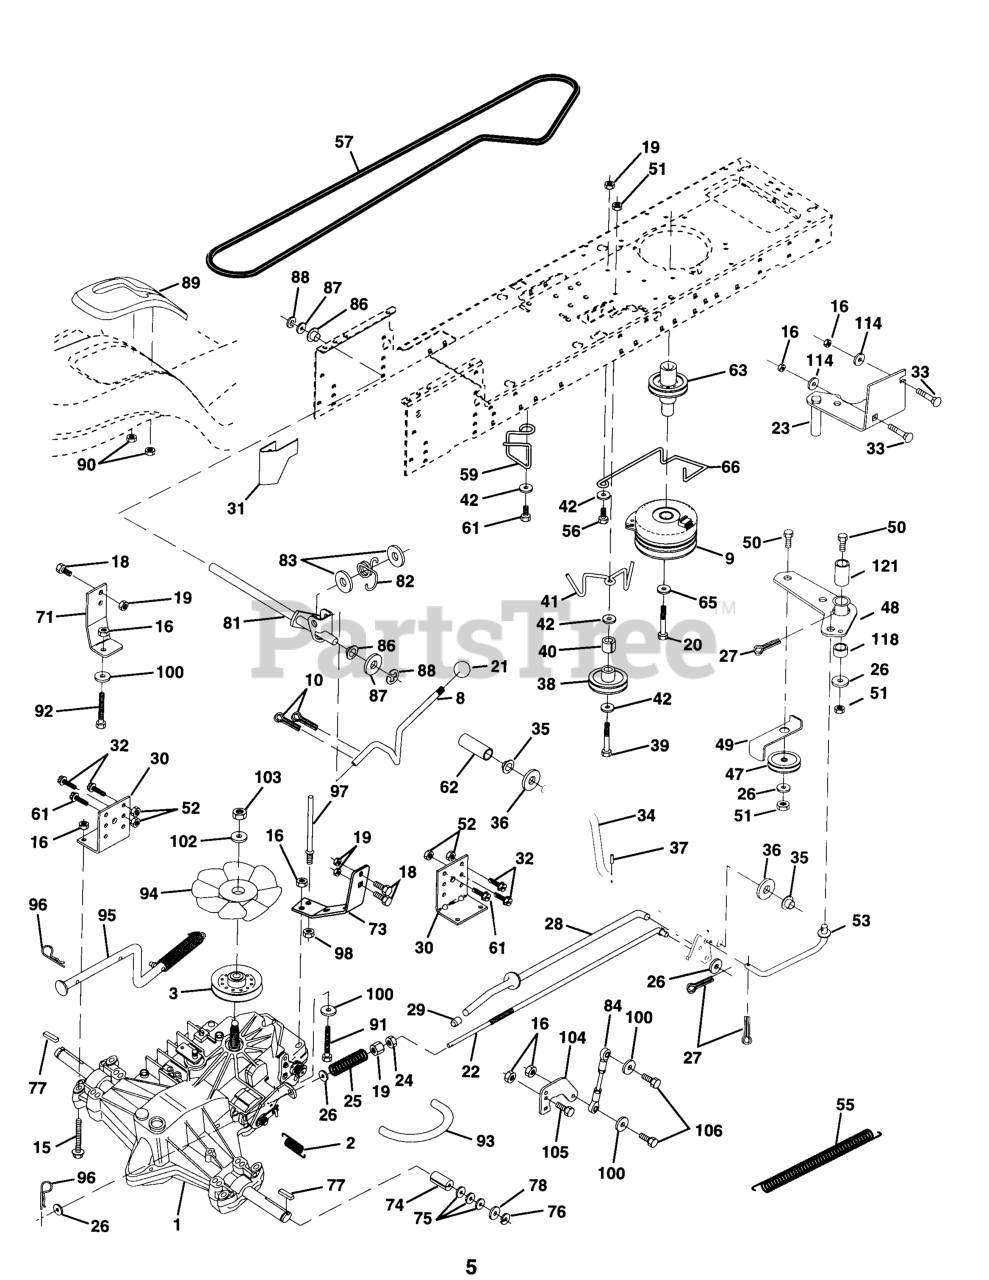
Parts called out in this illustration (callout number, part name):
2	SPRING BRAKE
3	PULLEY, TRANSAXLE
8	ROD SHIFT FENDER
9	CLUTCH.ELECT.EVX.
10	PIN COTTER
15	BOLT HEX 5/16-18 GR 5
16	NUT.71038.31-18.HEX.NYLOCK
18	BOLT
19	NUT
20	BOLT HEX
21	KNOB.DELUXE.(PISTOL.GRIP).BLAC
22	ROD BRAKE HYDRO
23	BRACKET, ASM CLUTCH MTG
24	NUT
25	SPRING ROD LT
26	WASHER
27	COTTER PIN
28	ROD BRAKE PARK LT
29	PLUNGER CAP
30	BRACKET TRANSAXLE
31	KEEPER BELT LH
32	BOLT
33	RP BOLT 5/16-18 X3/4 ZN/YEL GR
34	SHAFT, FOOT PEDAL
35	BEARING.NYLON
36	WASHER LT
37	DRIVE PIN
38	PULLEY.IDLER.FLAT
41	KEEPER, BELT IDLER
42	WASHER
47	IDLER PULLEY
48	BELLCRANK ASSEMBLY
49	RETAIN BELT
50	BOLT
52	LOCKNUT
53	LINK, CLUTCH LT
55	SPRING, RETURN LT
57	DRIVE BELT, LTH & YTH TRACTORS
59	KEEPER CENTER SPAN
61	SCREW
62	COVER, PEDAL (1 2)
63	PULLEY, CLUTCH ELECT EVX
65	LOCKWASHER
66	KEEPER BELT ENGINE
71	STRAP LH TORQUE
73	STRAP TORQUE RH HYDRO
74	SPACER SPLIT
77	SQUARE KEY
81	SHAFT ASSY
82	SPRING,TORSION
83	WASHER
84	ROD.TIE.BALL.4.75
86	BUSHING.STEERING.ROD LTB-WSL
89	CONSOLE SHIFT
90	NUT.PUSH.3/16
91	BOLT.FIN HEX 5/16-18UNC X2 1/4
92	HEX BOLT
93	LINE FUEL HYD 4"
94	FAN 7" HYDRO
95	CONTROL ARM, BYPASS HYDRO
96	RETAINER M
97	KEEPER BELT RH
100	WASHER M
103	NUT.HEX.1/2-20
104	CONTROL ARM
106	BOLT.5/16-18X1-1/4 FULL.THREAD
114	Washer 11/32 x 3/4 x 14 Ga.
118	SPACER BELLCRANK
121	NYLINER CLUTCHING
